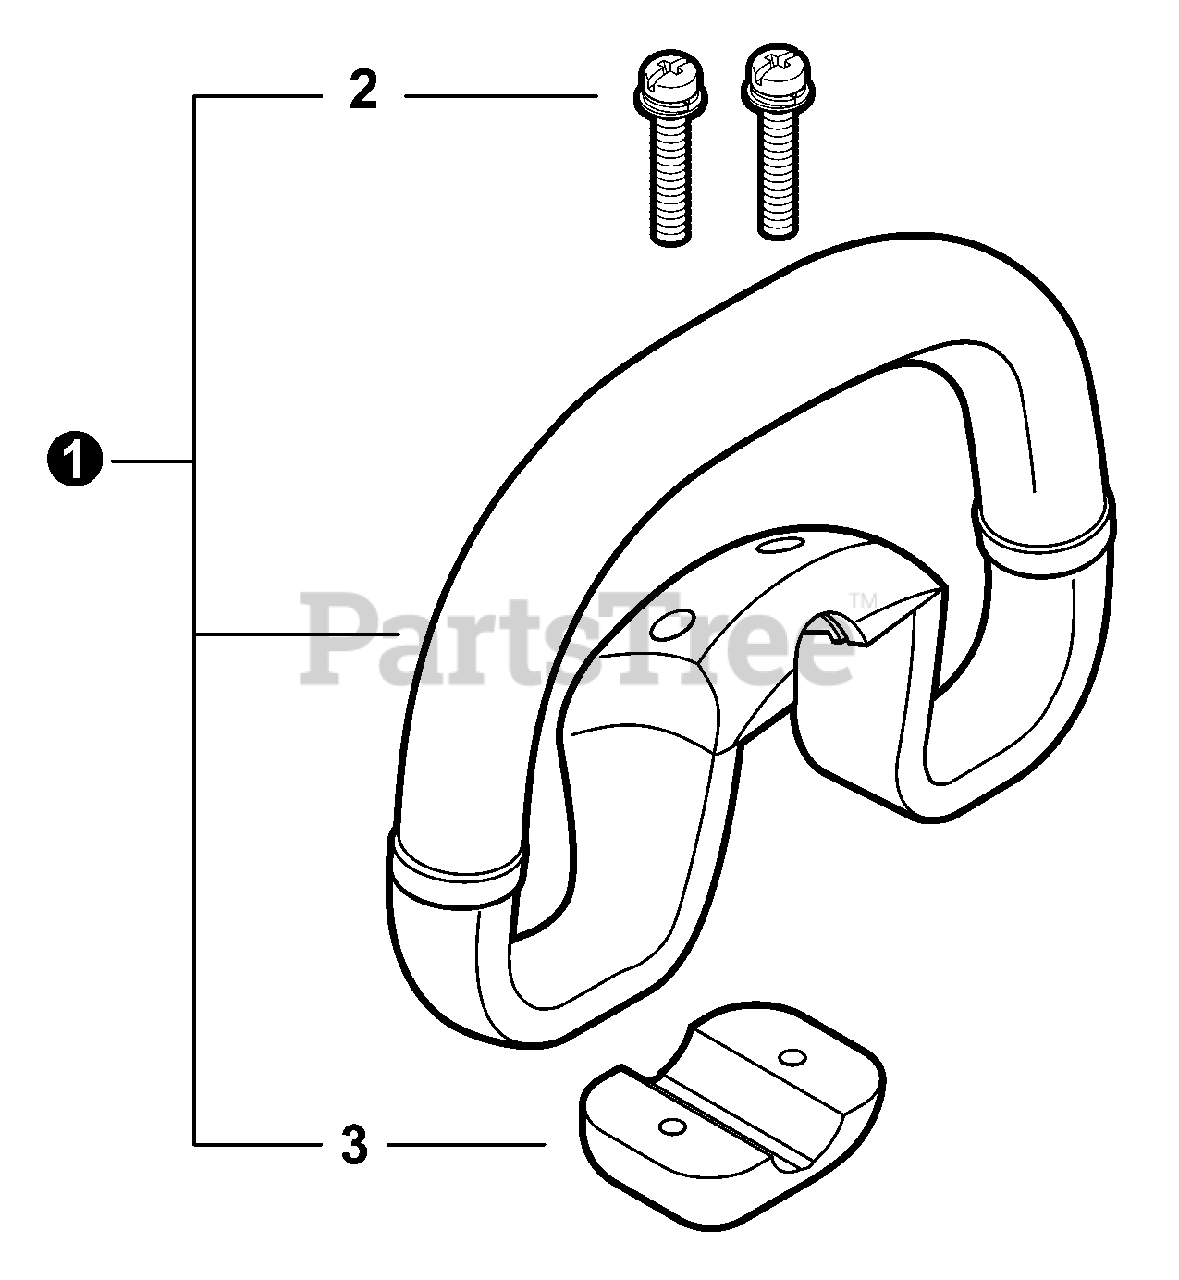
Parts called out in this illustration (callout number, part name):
1	HANDLE ASSY - SUPPORT
2	SCREW 5×40
3	BRACKET, HANDLE
